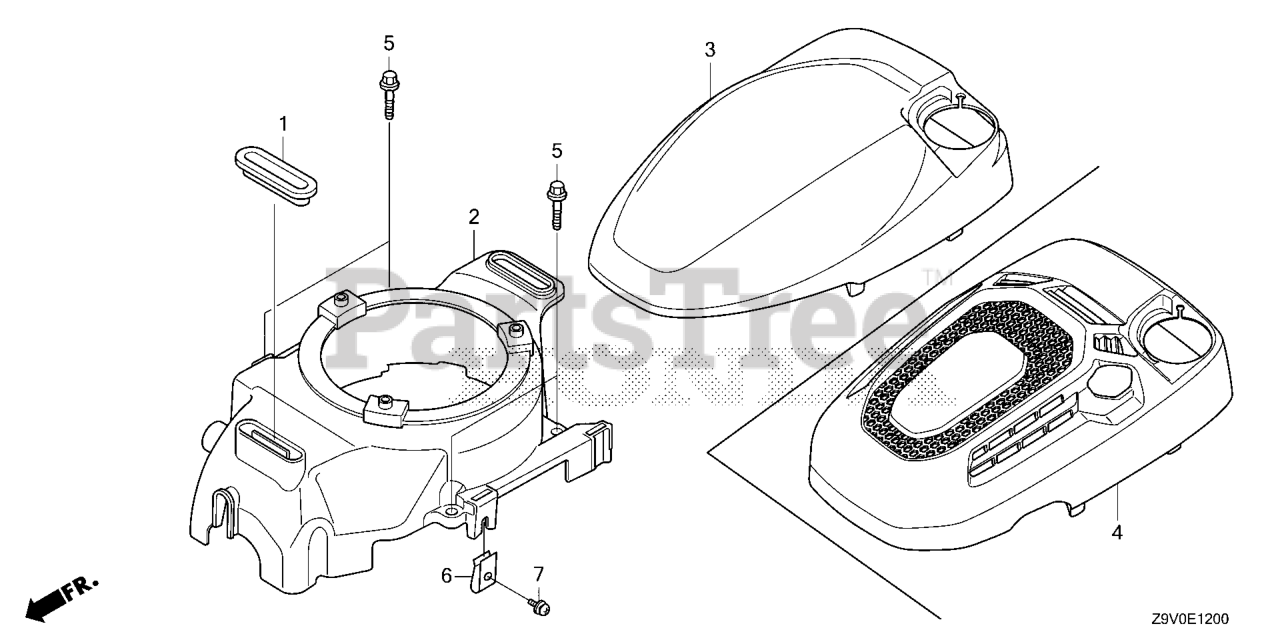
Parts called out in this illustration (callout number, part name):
1	RUBBER A, TANK MOUNTING
2	COVER, FAN
3	COVER, TOP *NH1* (BLACK)
3	COVER, TOP *T98* (MTD RED)
3	COVER, TOP *T89* (CRAFTSMAN RED)
3	COVER, TOP *T104* (RYOBI GREEN)
5	BOLT, FLANGE (6X23)
6	NUT, SPRING (5MM)
7	SCREW-WASHER (5X8)
